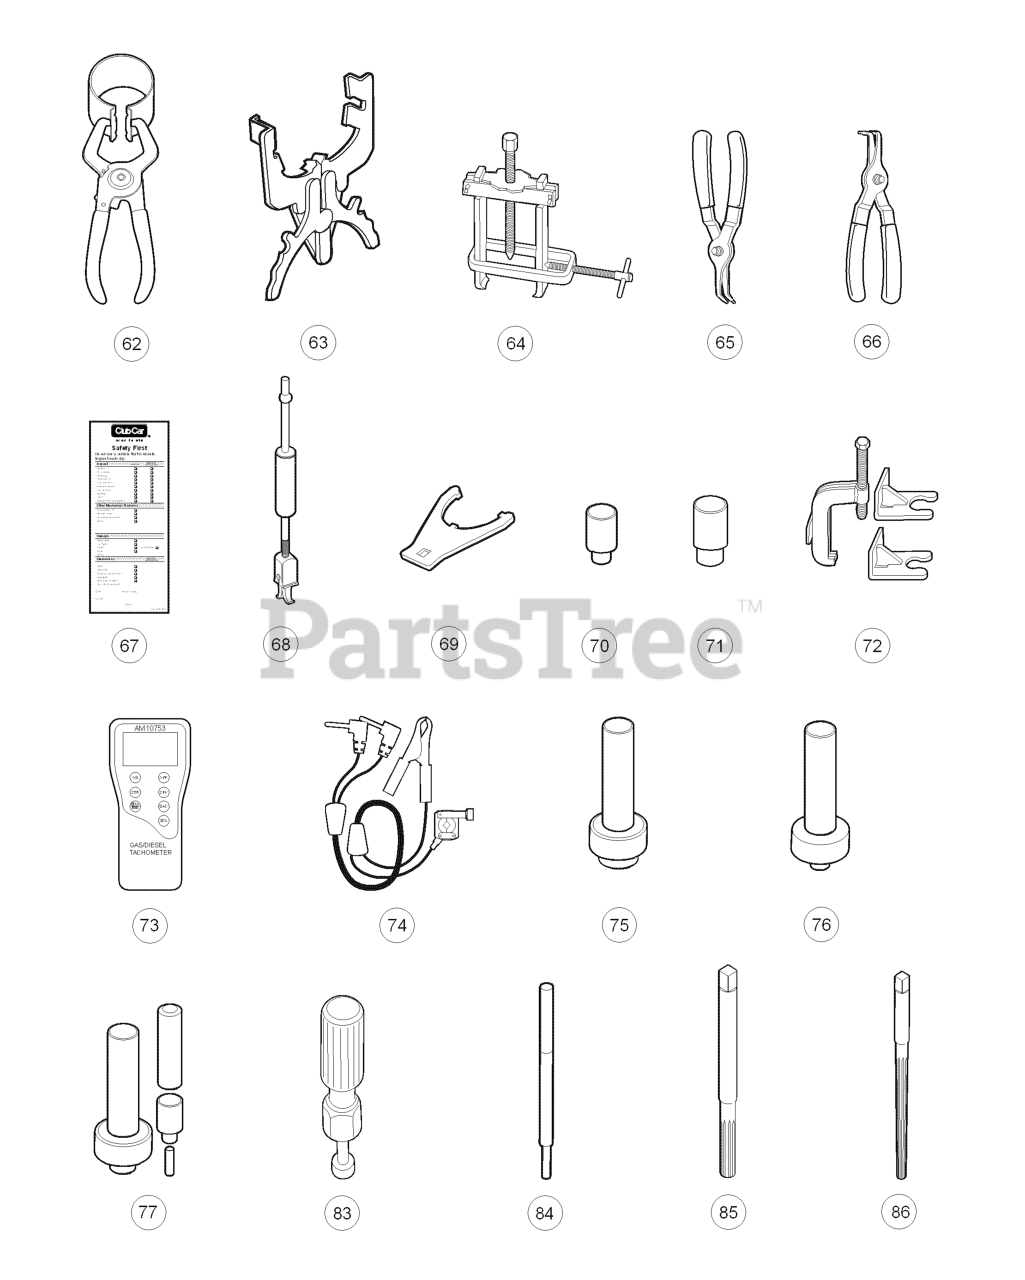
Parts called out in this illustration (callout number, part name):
62	KIT, PISTON RING COMPRESSOR
63	PISTON RING PLIER
64	SPECIAL-USE PULLER SET
65	EXTERNAL SNAP RING PLIERS
66	INTERNAL SNAP RING PLIER 9O
67	SAFETY FIRST CARD
68	SEAL PULLER
69	WRENCH, SPANNER
70	Steering Column Bearing Press Tool
71	TOOL-STEERING RETAINING RING
72	PULLER, STEERING WHEEL
73	TACHOMETER GAS/DIESEL
74	TACHOMETER DIESEL ADAPTOR
75	TRANS-AXLE, AXLE SEAL TOOL
76	Transaxle Pinion Seal Tool
77	Transmission Tool Kit
82	VALVE CLEAR ADJ SCREW HOLDER
83	DRIVER, VALVE GUIDE, 6.6. MM
84	VALVE GUIDE REAMER
85	REAMER-VALVE GUIDE
